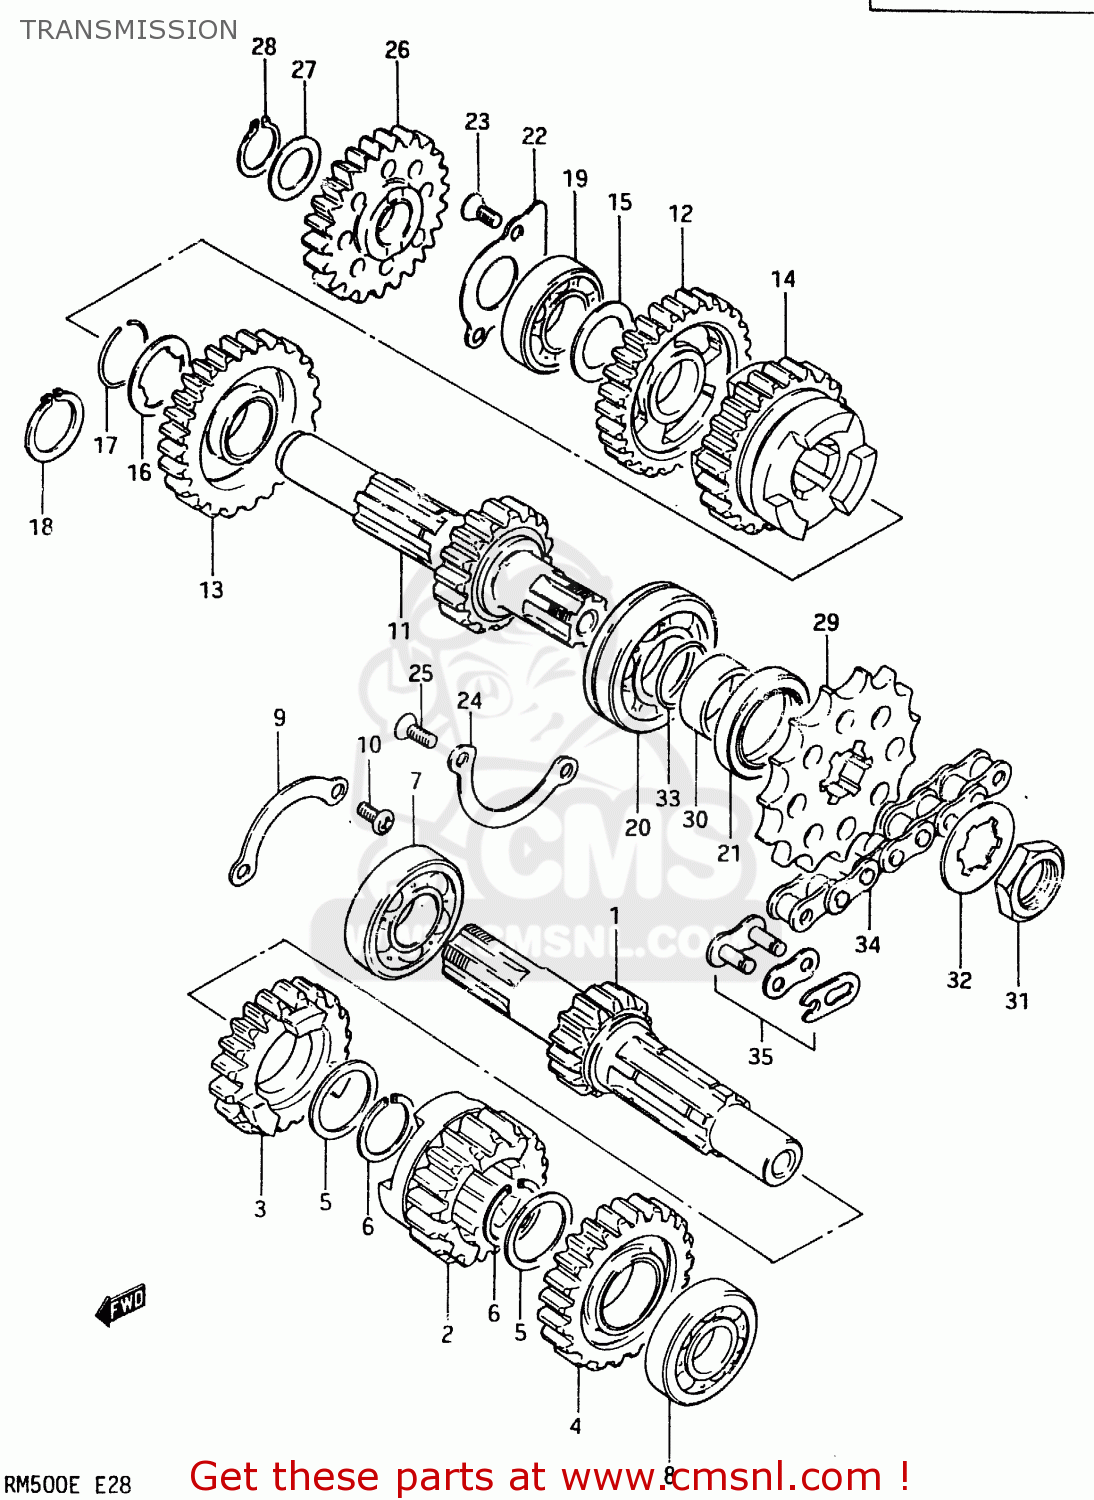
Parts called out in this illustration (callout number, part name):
1	SHAFT,COUNTER
2	GEAR,SECOND DRIVE
3	GEAR,THIRD DRIVE
4	GEAR,FOURTH DRIVE
5	WASHER
6	CIRCLIP
7	BEARING
8	BEARING, LH
9	RETAINER,BEARING
10	SCREW 6X12
11	SHAFT,DRIVE
12	GEAR,FIRST DRIVEN
13	GEAR,SECOND DRIVEN
14	GEAR,THIRD DRIVEN
15	WASHER
16	WASHER
17	CIRCLIP
18	CIRCLIP
19	BEARING
20	BEARING(28X58X16)
21	SEAL,OIL(35X45X6)
22	RETAINER,DRIVESHAFT
23	SCREW
24	PLATE,DRIVESHAFT BEARING
25	SCREW
26	GEAR,KICK STARTER IDLE
27	WASHER,THRUST
28	CIRCLIP
29	SPROCKET,ENGINE(NT:13)
30	SPACER(28X35X11.4)
31	NUT
32	WASHER,LOCK
33	O RING(D:1.5,ID:27.7)
34	CHAIN ASSEMBLY,DRIVE
35	JOINT ASSEMBLY,CHAIN
